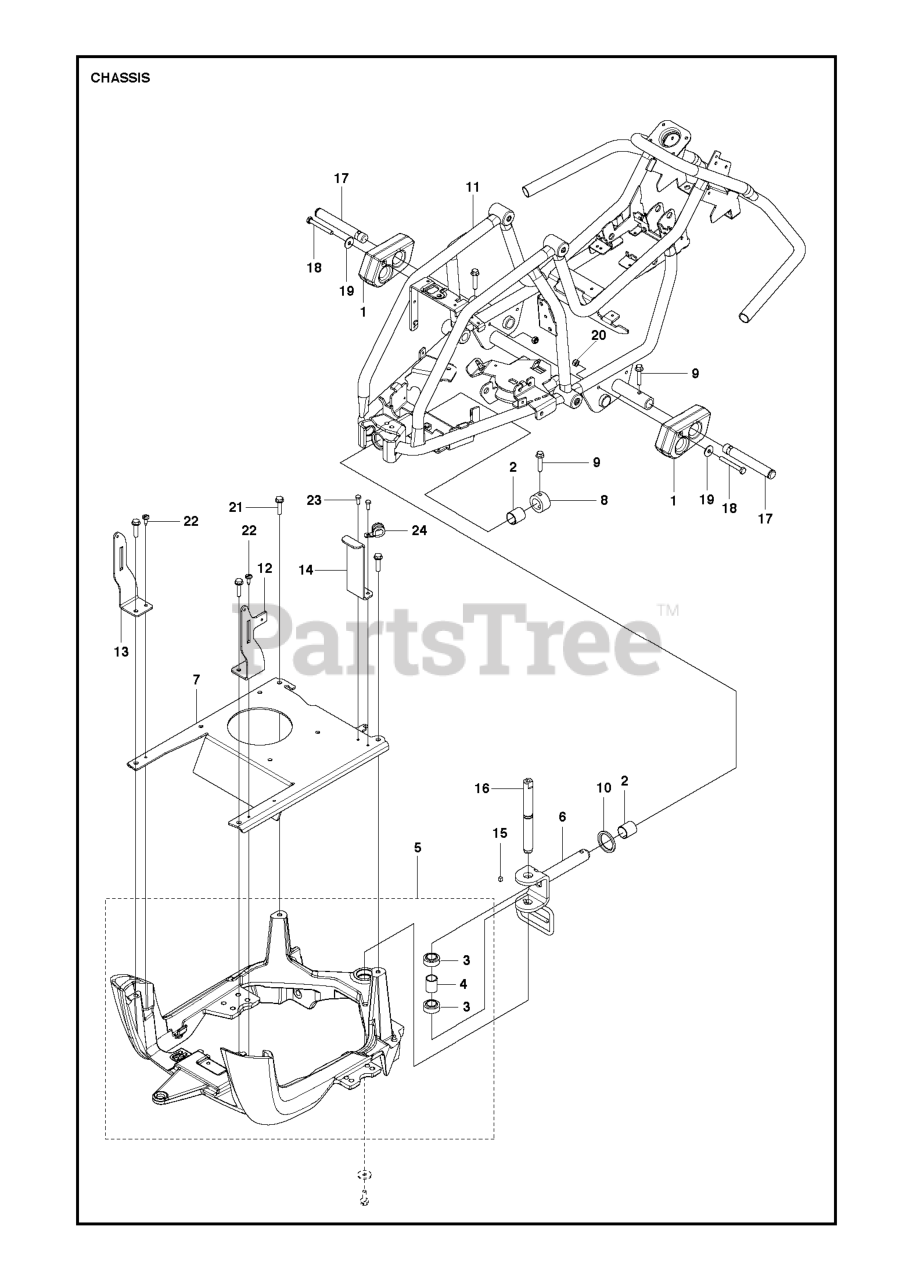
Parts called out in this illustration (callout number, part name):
1	COUNTERWEIGHT
2	BUSHING
6	SWING AXLE
8	STOP SLEEVE
9	BOLT FLANGE - M8X40\
11	FRAME FRONT ASSY
17	WHEEL AXLE
20	LOCKNUT M8
21	SCREW EHHFM
23	SCREW
24	HOSE CLAMP
